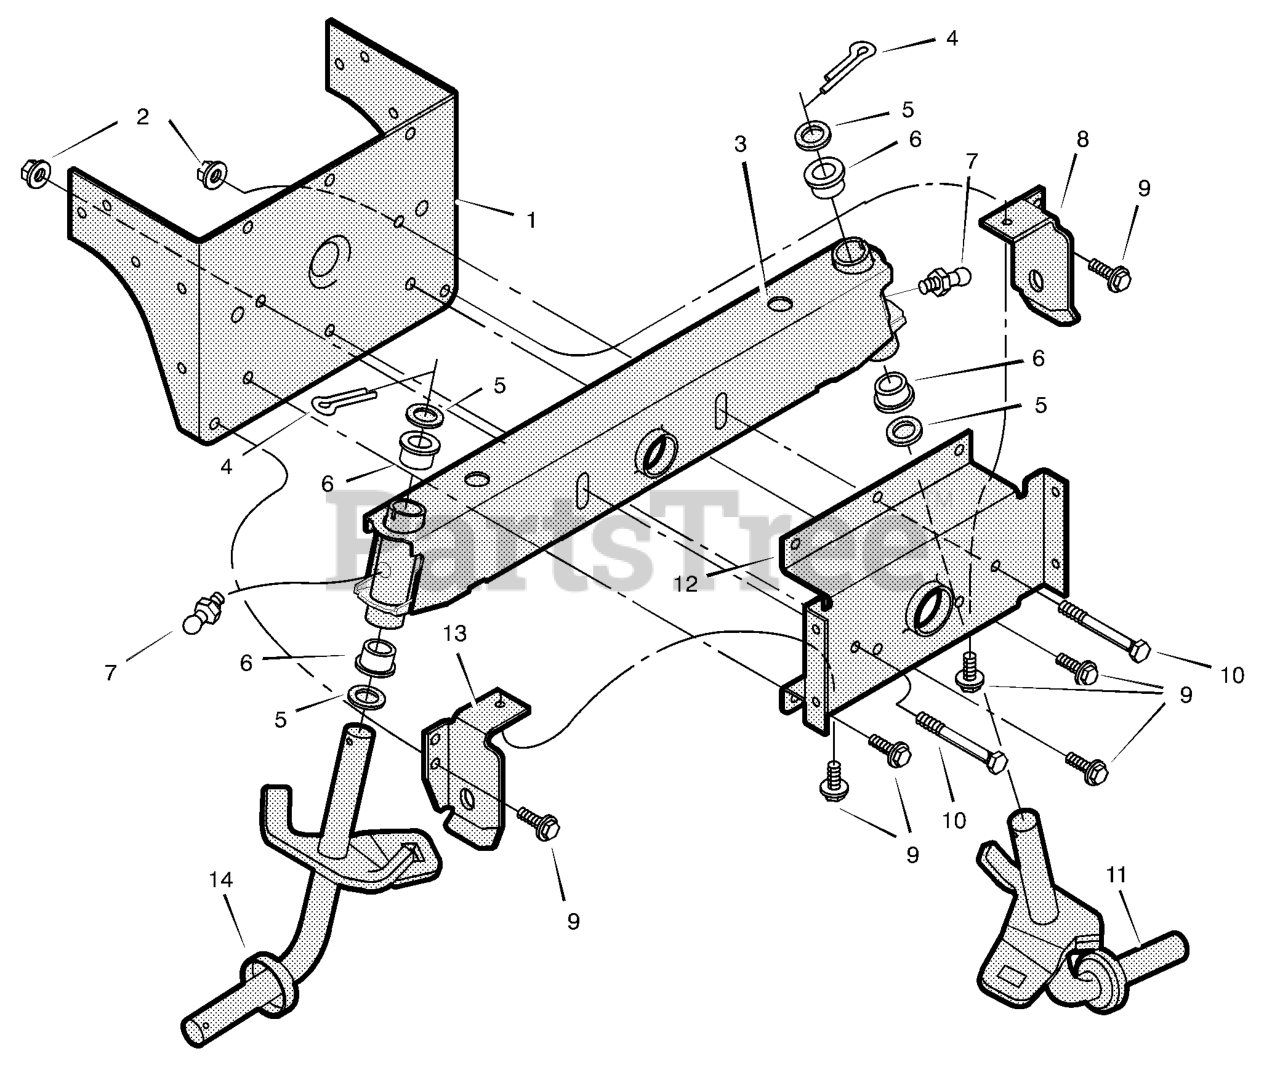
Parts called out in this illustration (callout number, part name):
1	Bracket, Rear Hanger
2	Nut, Flange
3	Axle Assembly -with fitting
4	Pin, Hair
6	Bearing, Spindle
7	Fitting, Lub
8	Hanger, Left Deck
11	Spindle Assembly, Left
12	Hanger, Axle
13	Hanger, Right Deck
14	Spindle Assembly, Right
